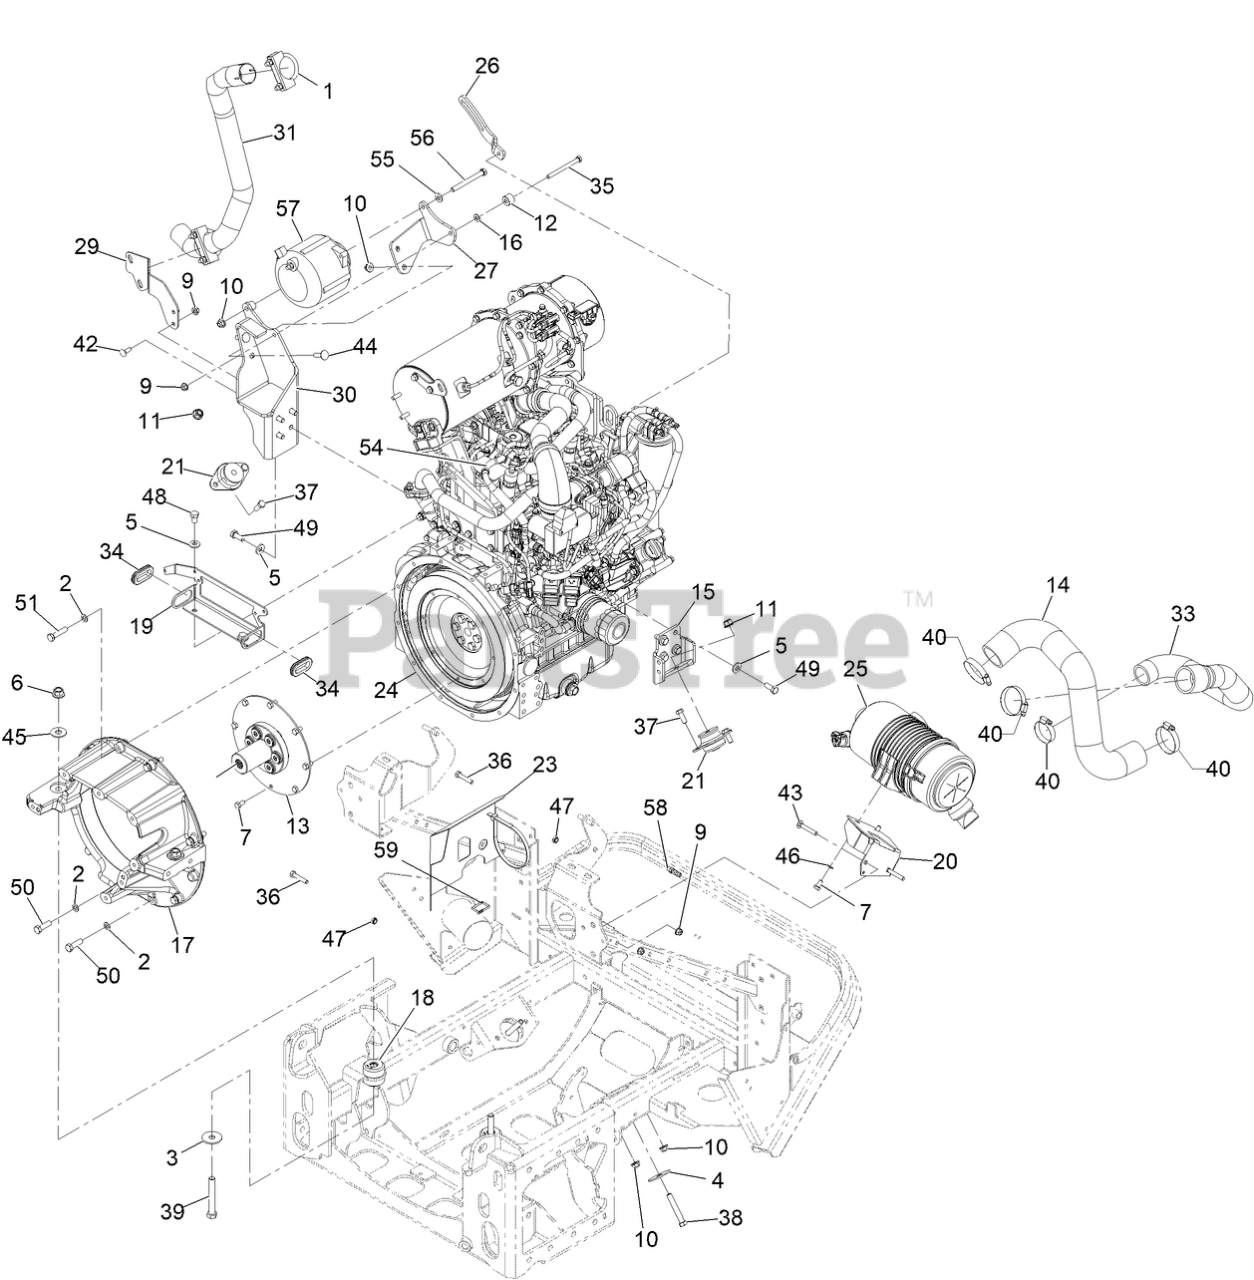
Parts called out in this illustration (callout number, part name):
1	CLAMP
2	WASHER-LOCK
3	WASHER-THRUST
4	WASHER-SNUBBING
5	WASHER-BELLEVILLE
6	NUT-LOCK
7	BOLT
9	NUT-HF, NI
10	NUT-HF, NI
11	NUT-HF, NI
12	SPACER
13	COUPLING-FLYWHEEL
14	HOSE-AIR
15	MOUNT-MOTOR, UPPER
16	WASHER-PLAIN
17	HOUSING-FLYWHEEL
18	MOUNT-ISOLATOR
19	PLATE_GUIDE BRACKET
20	BRACKET-CLEANER, AIR
23	DEFLECTOR-AIR
24	ENGINE-YANMAR, 3TNV86CT-DTR2
25	ASM, HDAC
26	TENSION ARM-ALTERNATOR
27	BRACKET, ALTERNATOR
29	EXHAUST BRACKET
30	MOUNT ASM-UPPER [BLACK]
31	TUBE-EXHAUST
33	HOSE-AIR
34	GROMMET-RUBBER
35	SCREW-HH
36	SCREW-HH
37	SCREW-HH
38	SCREW-HH
39	SCREW-HH
40	CLAMP-HOSE
42	SCREW-CARR
43	BOLT-CARR
44	BOLT-CARR
45	WASHER-FLAT
46	WASHER-BELLEVILLE
47	NUT-LOCK, NI
48	SCREW-HH
49	SCREW-HH
50	SCREW-HH
51	SCREW-HH
54	INSULATION-HEAT
55	WASHER-HARDENED
56	SCREW-HH
57	ALTERNATOR-12V 175A
58	FITTING-STRAIGHT
59	TIE-CABLE, SS
